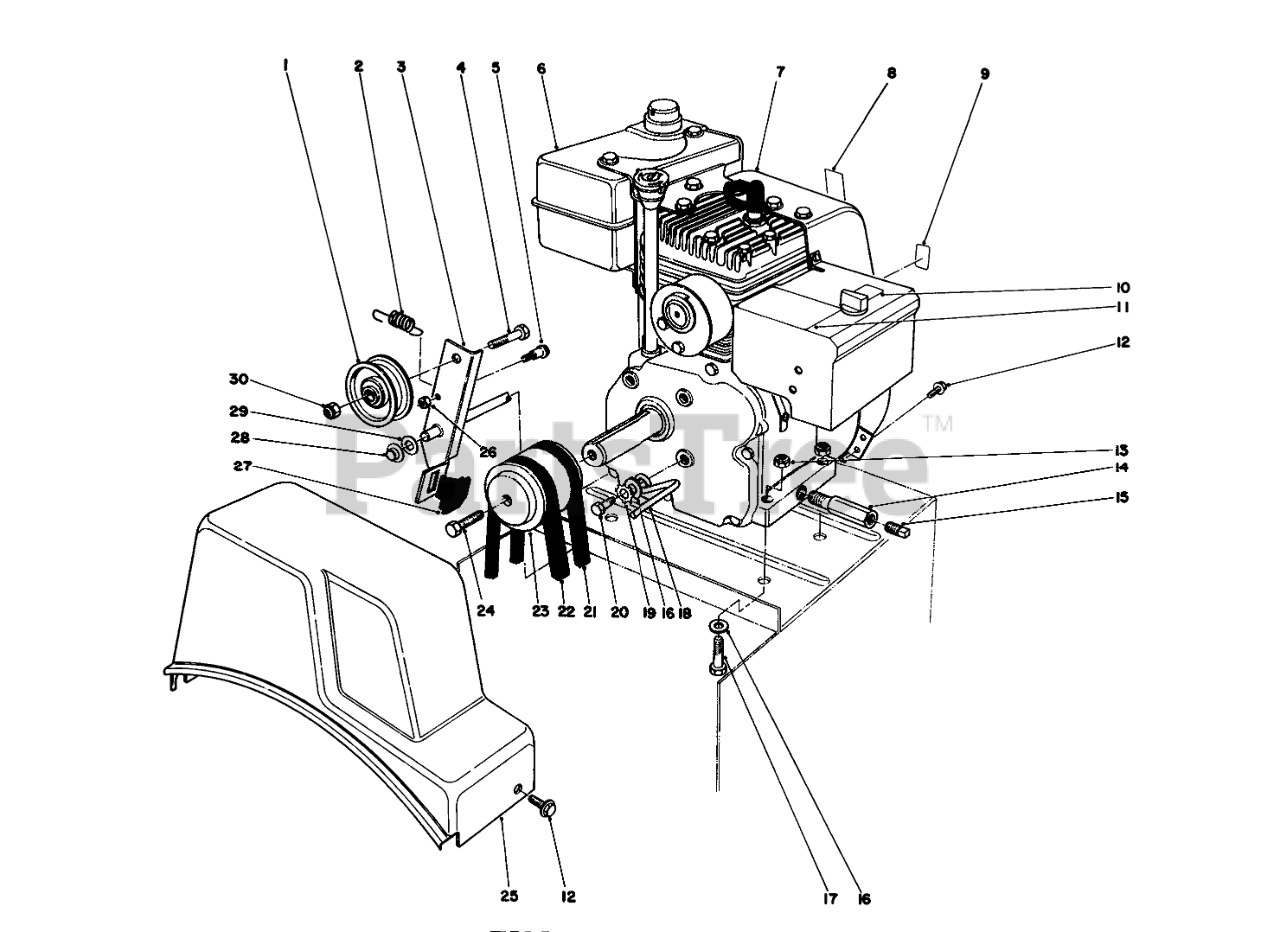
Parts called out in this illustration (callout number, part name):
1	PULLEY-IDLER
2	SPRING
3	Auger Clutch Rod Assembly (Incl. Ref. #27)
4	SCREW-HH
5	BOLT-SHOULDER
6	GAS TANK 2 QT W CAP
7	Engine
8	PRIMER DECAL
9	DECAL THROTTLE
10	CHOKE DECAL
11	Decal Hot Surface Warning
12	SCREW
13	NUT-LOCK, NI
14	PIPE-NIPPLE
15	CAP-PIPE
16	WASHER-PLAIN
17	SCREW-HH
18	RETAINER-BELT
19	WASHER-LOCK
20	SCREW-HH
21	V BELT-3L, TRACTION
22	V-BELT (29.50 INCH)
23	PULLEY-ENGINE
24	SCREW-SPECIAL
25	COVER-BELT
26	NUT-LOCK, NI
27	Brake Pad
28	RETAINER-PUSH ON
29	WASHER-FLAT
30	NUT-LOCK, CONE
